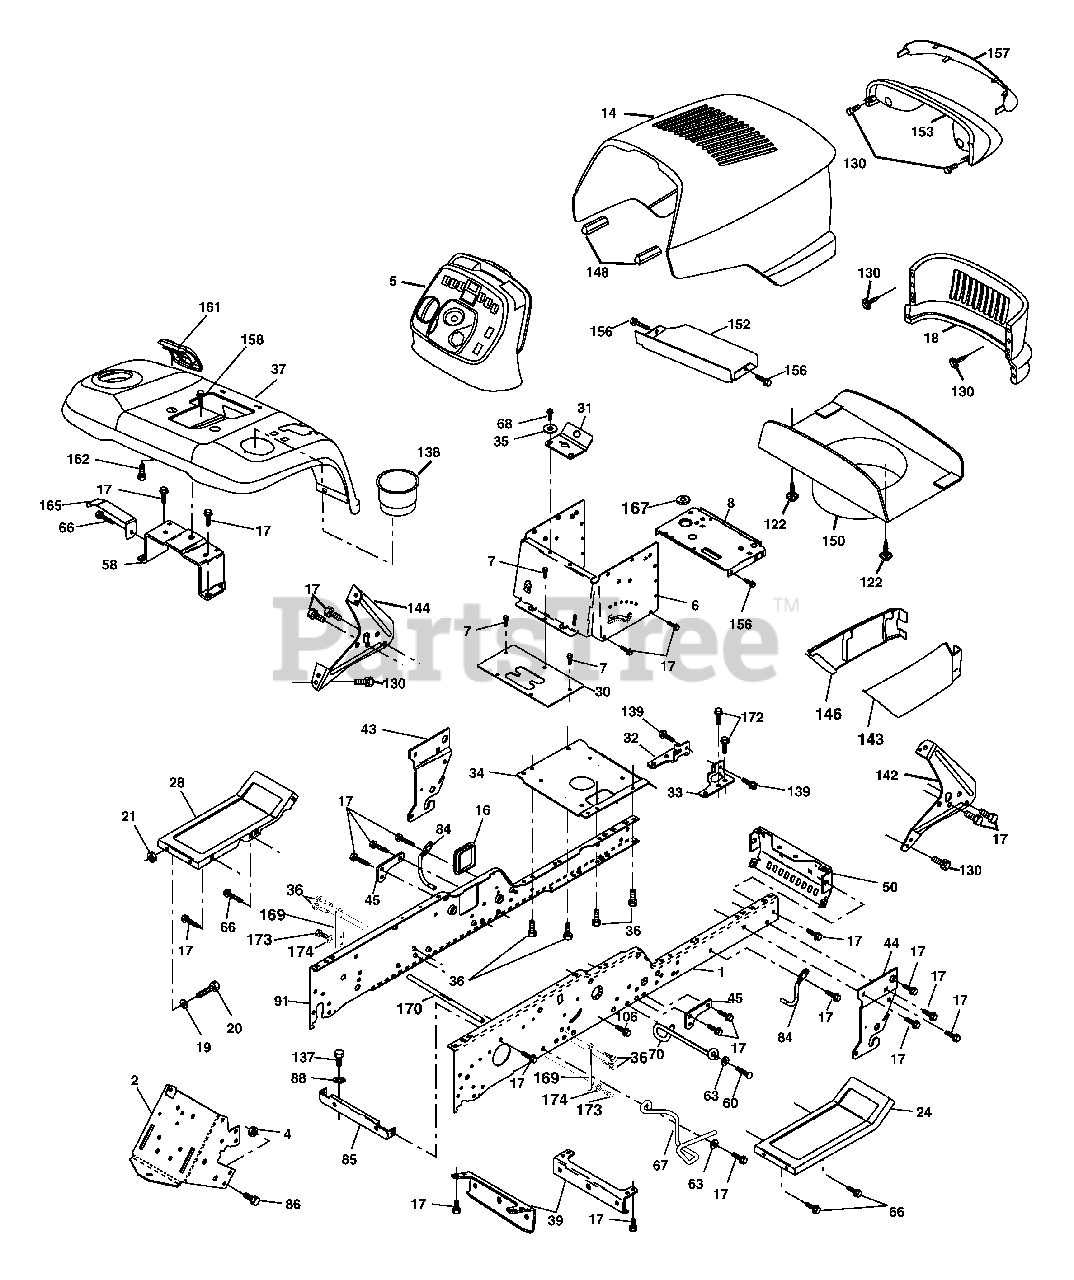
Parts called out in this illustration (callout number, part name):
1	Rail, Frame RH
2	Drawbar, Gt
4	Nut, Crownlock Hex 7/16-14 unc
5	Dash
6	Dash, Lower Vgt One Piece
7	Screw, Thd Cut 1/4-20 x 1/2
8	Support, Battery
14	Hood Asm
16	Cover, Access
17	Screw 3/8-16 x 3/4 Zc
18	Grille
19	Washer 13/32 x 13/16 x 12 Ga.
20	Bolt Fin Hex 3/8-16 x 1 Gr. 5
21	Nut Lock 3/8-16 unc
24	Footrest, RH
28	Footrest, LH
30	Saddle, Slkscr Vgt
31	Bracket Support 1-pc
32	Bracket, Pivot Chassis Lh
33	Bracket, Pivot Chassis Rh
34	Plate Asm Engine Chassis
35	Washer 11/32 x 11/16 x 16 Ga.
36	Screw 5/16-18 x 3/4
37	Fender
39	Bracket, Axle Front
43	Bracket, Spnsn Front Lh
44	Bracket, Spnsn Front Rh
45	Bracket Chassis
50	Bracket, Chassis Front
58	Bracket Fender
60	Screw 3/8-16 x 1-1/4
63	Washer 13/32 x 1 x 14 Ga.
66	Screw 3/8-16 x 1/2
67	Guide, Belt Gear Drive
68	Screw Thdrol. 5/16-18 x 1/2
70	Guide, Belt
84	Up Stop
85	Bracket, Support Transaxle
86	Bolt Fin Hex 7/16-14 unc x 1
88	Washer, Lock Hvy Hlcl Spr 7/16
91	Rail, Frame Lh
106	Screw Thdrol 5/16-18 x 1.25
122	Screw Wshd Hex 10-32 x 5/8
130	Screw 10 x 3/4 Single Lead-Hex
137	Bolt Fin Hex 7/16-14 x 1 Gr. 5
138	Cupholder YTGT
139	Bolt Shoulder 5/16-18 TT
142	Bracket Dash Rh
143	Skirt Grille RH
144	Bracket Dash Lh
146	Skirt Grille LH
148	Extrusion Bumper
150	Duct Heat Hood
152	Shield Browning
153	Light Box Asm w/Lens
156	Screw 5/16-18 x 3/4. Blk
157	Lens Bar
158	Screw Thdrol. 3/8-16 x 1/2
161	Console Fuel Window
162	Screw Hex Wsh Hi-Lo 1/4-1/2
165	Bracket Support Tank
167	Bushing Snap
169	Bracket Chassis Sway
170	Rod Bracket Sway Brace
172	Screw 3/8-16 x .875
173	Bolt Fin Hex 5/16-18 UNC x 3/4
174	Washer Lock Hvy HLCL Spr 5/16
